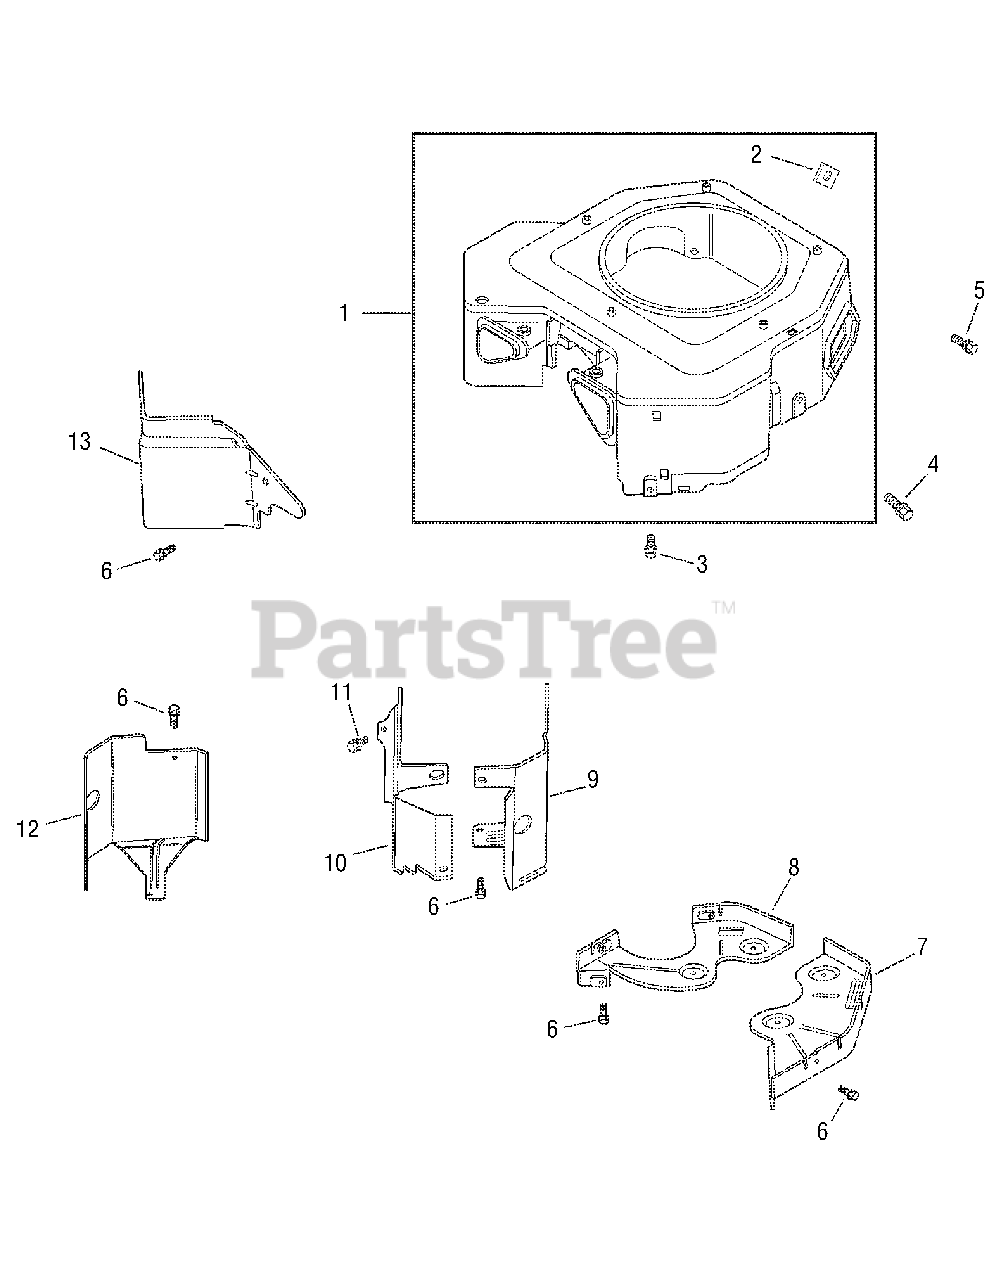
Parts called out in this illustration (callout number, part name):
1	Housing, blower (Includes Ref 2, KH-24-096-85-S & KH-25-086-92-S)
2	Nut, plastic
3	Screw, hex. Flange M5 x 0.8 x 20
4	Screw, hex. Flange M5 x 0.8 x 16
5	Screw, hex. Flange M5 x 0.8 x 16
6	Screw, hex. Flange M6 x 1.0 x 16
7	Plate, backing – #2 side
8	Plate, backing – #1 side
9	Baffle, cylinder barrel-#2 side
10	Baffle, valley-#1 side
11	Screw, hex. Flange M5 x 0.8 x 10
12	Baffle, cylinder barrel - #1 side
13	Baffle, valley – #1 side
